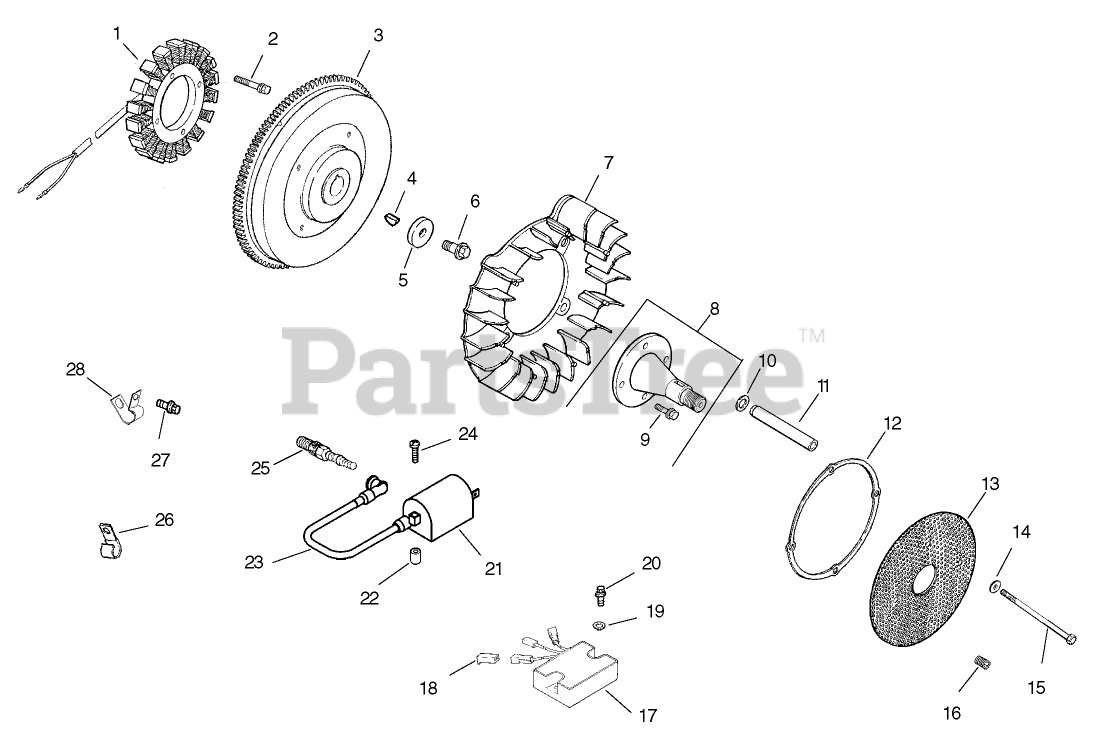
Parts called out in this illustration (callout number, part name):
1	STATOR ASM (25 AMP)
2	Screw-Cap, Hex (M5x0.8x30)
3	Flywheel
4	KEY (3/16 X 5/8)
5	WASHER-FLAT (13/32)
6	SCREW-FLANGE (M10X1.5X45)
7	Fan
8	Kit, front drive shaft (Includes 9)
8	Washer-Spring (10MM)
9	Screw-HF (M8x1.25x25)
9	Spacer
10	Ring-Support
11	Screen-Grass
12	WASHER-FLAT (1/4)
13	Screw-HH (M6x1.0x100)
14	Screw-Set (10-24X.25)
15	Rectifier-Regulator (15 amp)
16	Connector (3 contact)
17	WASHER-FLAT (.188)
18	SCREW-PHL HD (11-16X.88)
19	Coil-Ignition
20	Spacer
21	Spark Plug Boot ASM
22	Screw-Tapping
23	Spark Plug
24	Clip-Cable
25	SCREW-FLANGE, THREAD FORMING (M5X0.8X16)
26	Clamp-Hose
